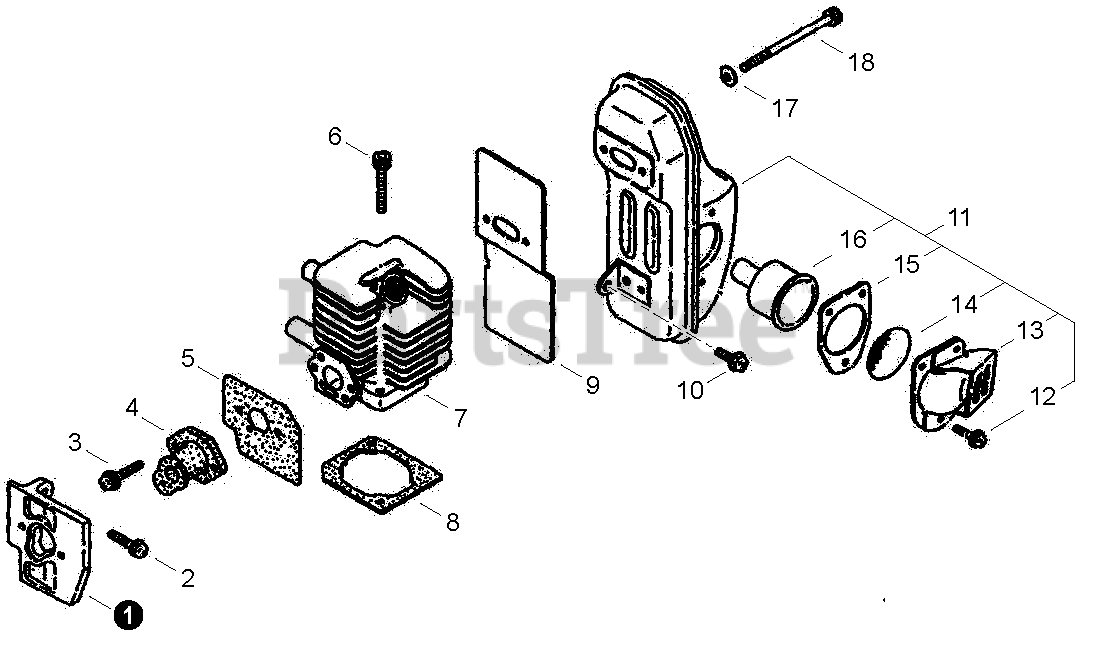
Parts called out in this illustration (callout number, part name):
1	INSULATOR, INTAKE
2	SCREW
3	SCREW
4	BELLOWS, INTAKE
5	GASKET, INTAKE
6	BOLT 5×20
7	CYLINDER
8	GASKET, CYLINDER
9	HEAT SHIELD, EXHAUST
10	SCREW
11	MUFFLER ASSY
12	SCREW
13	GUIDE, EXHAUST
14	SCREEN, SPARK ARRESTER
15	GASKET, EXHAUST
16	GUIDE, EXHAUST
17	WASHER, FLAT 5.5×10×0.8
18	BOLT 5×55
